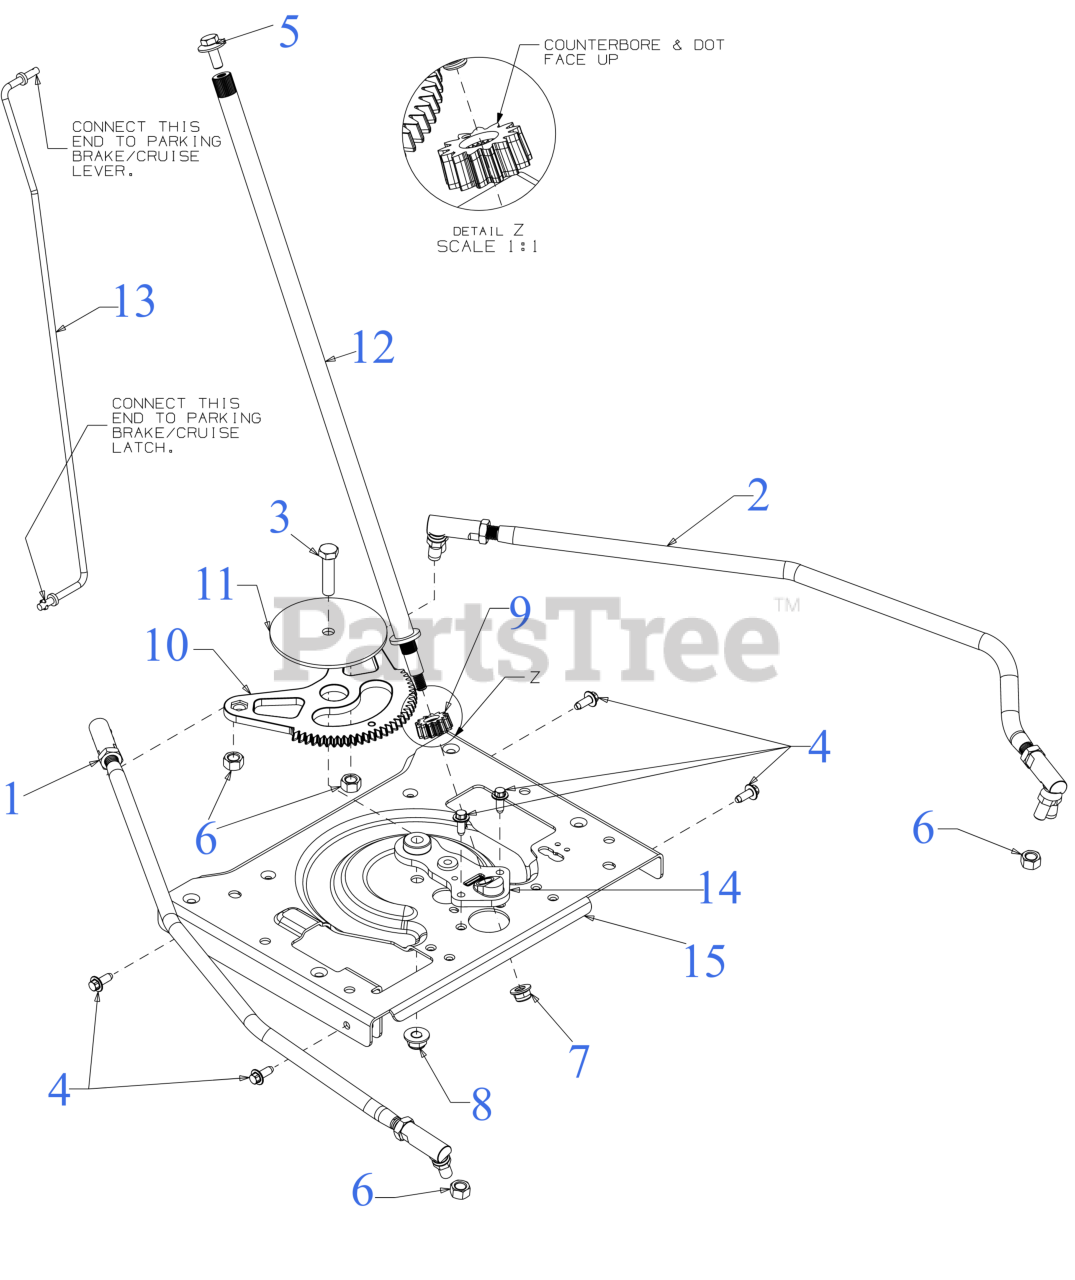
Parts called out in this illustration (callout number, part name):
1	STEERING DRAG LINK (RH)
2	STEERING DRAG LINK (LH)
3	SCREW 3/8-16 x 1.50
4	SCREW M6-1 x .625
5	SCREW 5/16-24 x .85 GR5
6	HEX NUT 3/8-24
7	FLANGE LOCK NUT 5/16-18
9	STEERING PINION GEAR 13T
10	STEERING GEAR SEGMENT 16"
11	FLAT WASHER .385 x 3.75 x .120 THK
12	STEERING SHAFT .625 x 20
13	CRUISE/BRAKE ROD
14	STEERING SUPPORT BEARING
